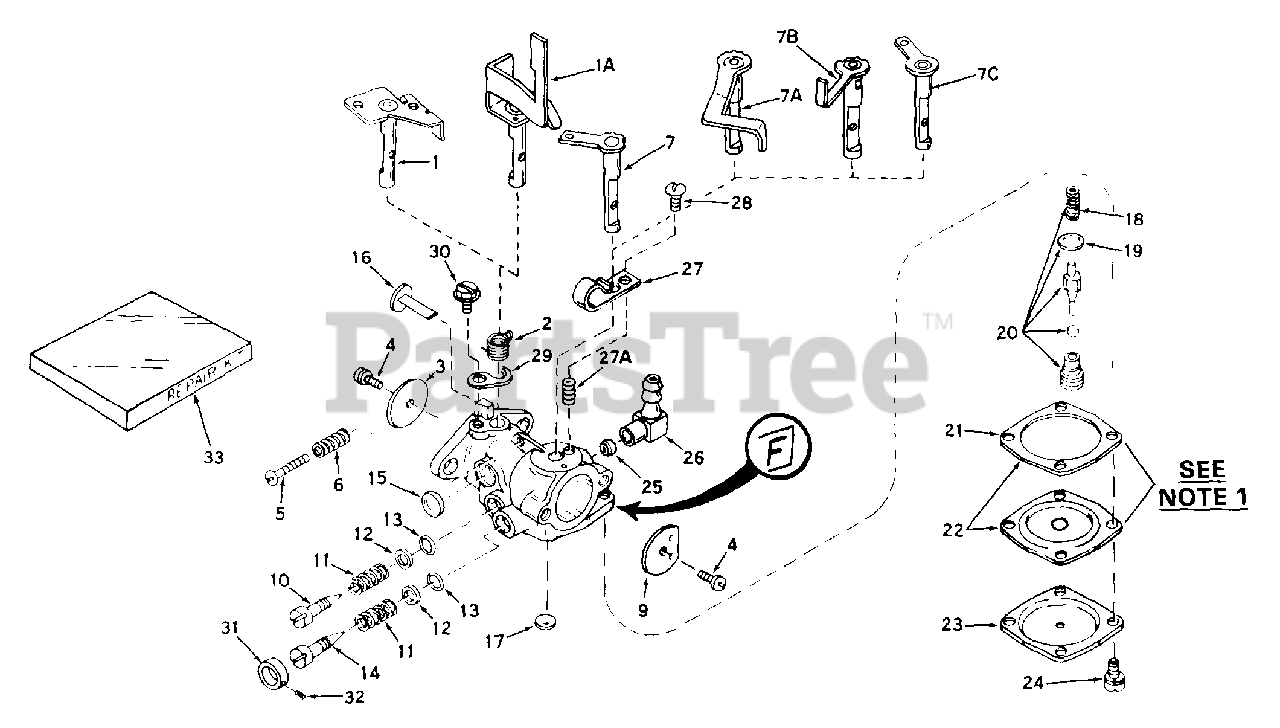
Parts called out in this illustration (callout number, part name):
1	"Shaft & Lever Assy., Throttle
2	Spring, Throttle return
3	Shutter, Throttle
4	Screw, Shutter, 4-40 x 3/16
5	Screw, Idle regulating, 8-32 x 3/4
6	Spring, Idle speed screw
7B	Shaft, Lever Assy., Choke
9	Shutter, Choke
10	Screw, Idle adjustment
11	Spring, Adjustment screw
12	Washer, Adjustment screw
13	"O" Ring, Adjustment screw
14	Screw, Main adj.
15	Plug, Welch
17	Plug, Welch
18	Spring, Valve
19	Gasket, Valve seat
20	Inlet Needle, Seat, Gasket & Spring A ssy.
21	Gasket, Diaphragm
22	Diaphragm Assy.
23	Cover, Diaphragm
24	Screw, Cover
26	Fitting, Fuel line
27	Spring, Detent
29	Retainer, Throttle shaft
33	Repair Kit
